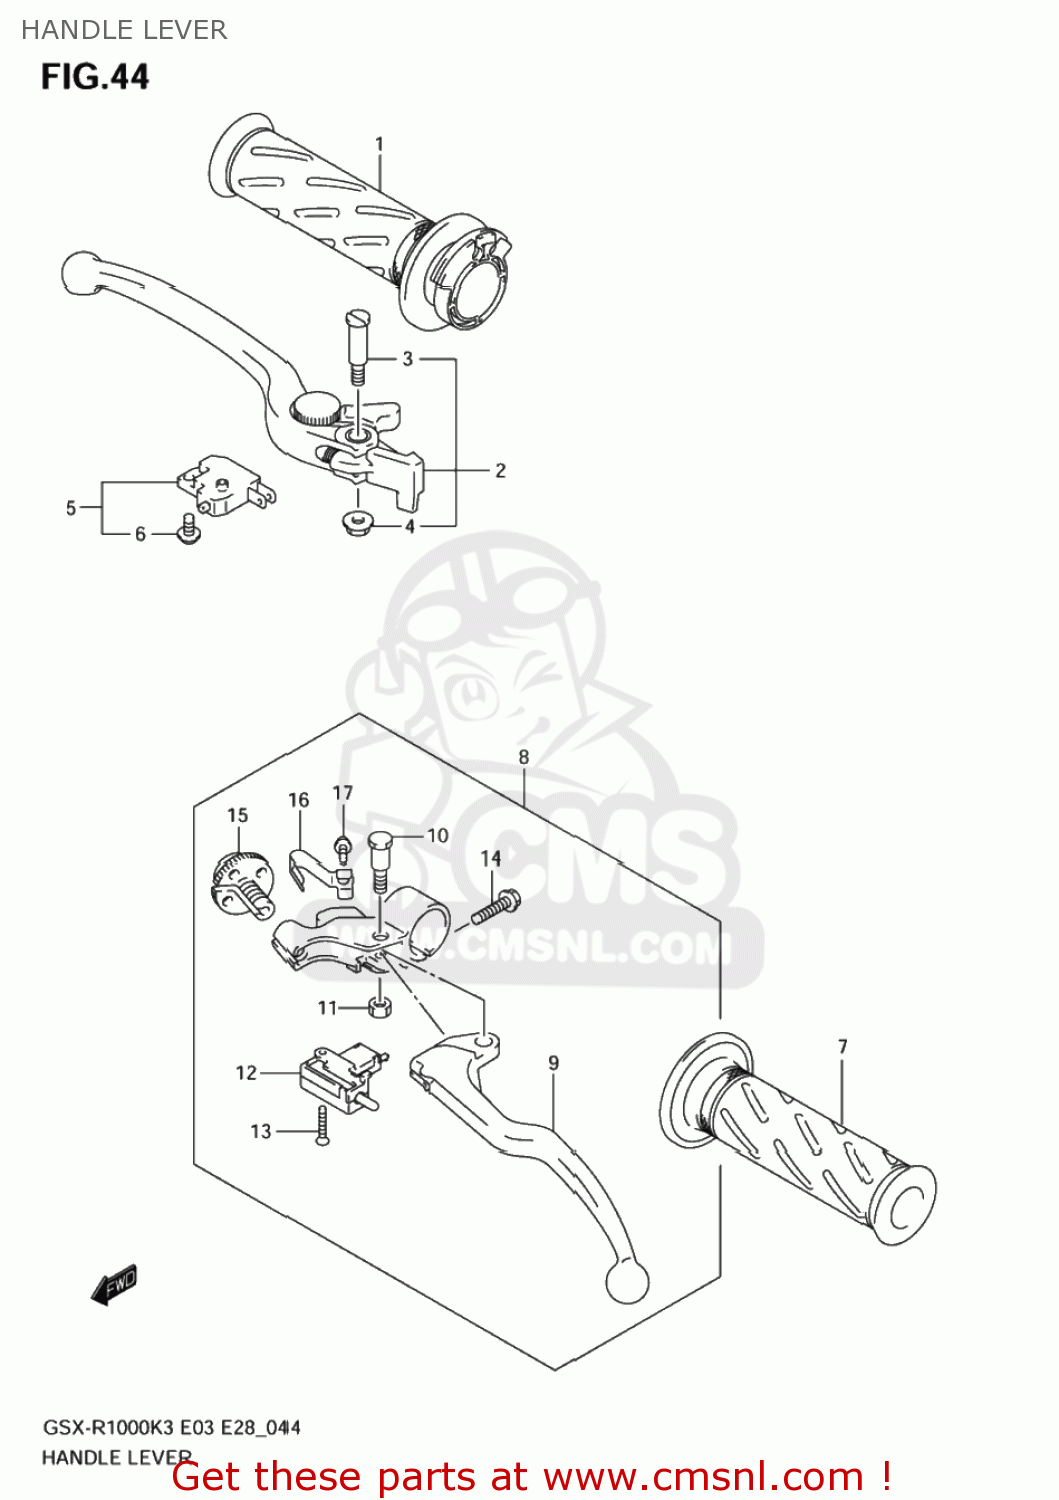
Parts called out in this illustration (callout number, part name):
1	GRIP,THROTTLE
2	LEVER ASSY,BRAKE
3	BOLT,LEVER PIVOT
4	NUT
5	SWITCH ASSY,ST
6	SCREW
7	GRIP,LEFT
8	LEVER ASSY,CLU
9	LEVER,CLUTCH
10	BOLT,LEVER PIVOT
11	NUT
12	SWITCH,CLUTCH
13	SCREW
14	SCREW
15	NUT,CABLE ADJUSTER
16	SPRING,ADJUST
17	SCREW,SPRING
